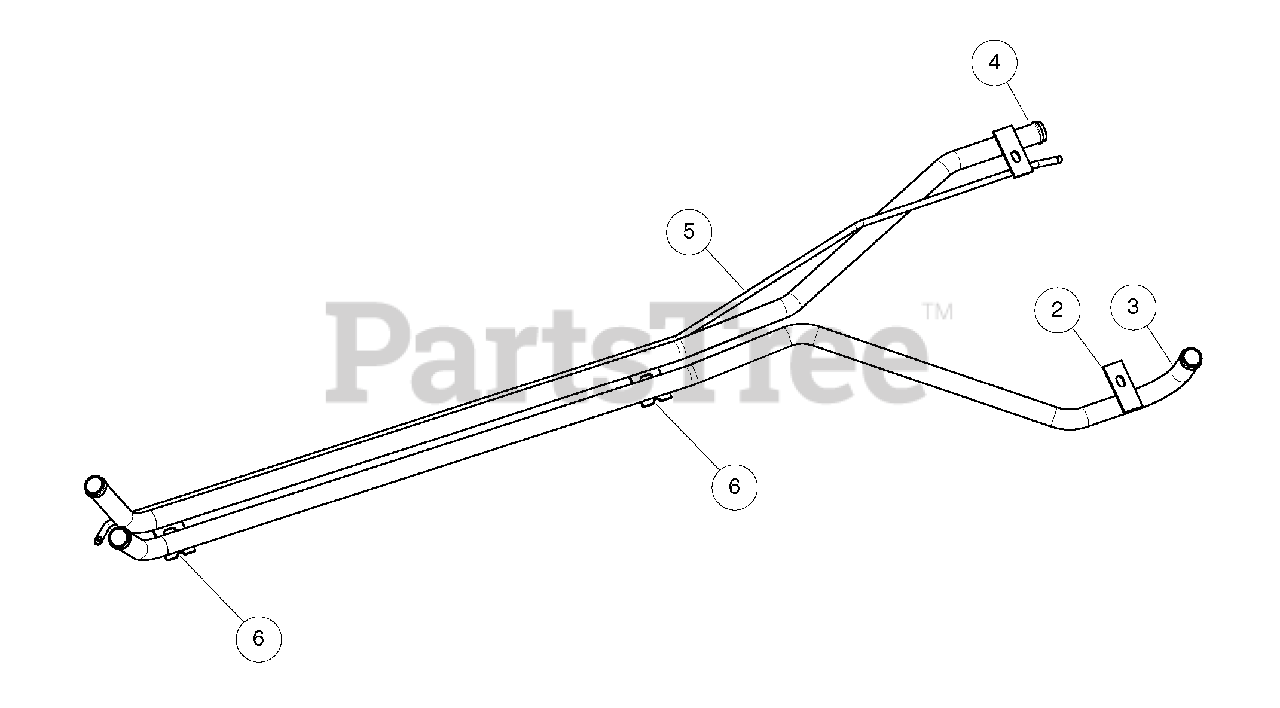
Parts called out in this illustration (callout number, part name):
1	Weldment, Group, Coolant Pipe
2	Tab, Rear Mntg, Coolant Pipe
3	Pipe, Coolant Upper, Stretch
4	Pipe, Coolant Lower, Stretch
5	Pipe, Vent, Coolant, Stretch
6	Tab, Cooling Pipe Mount
